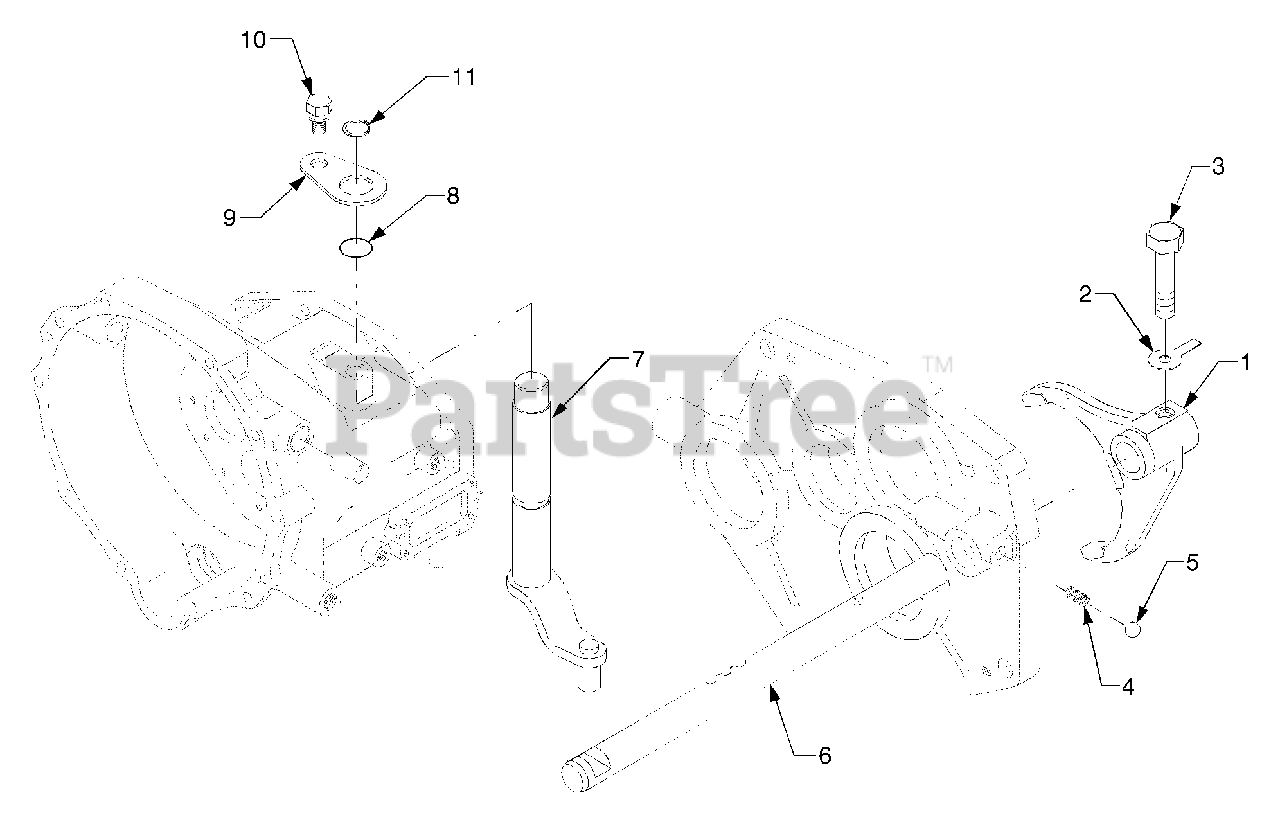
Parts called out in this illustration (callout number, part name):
1	Fork, Shift (Shuttle)
3	Bolt, Stopper
6	Rod, Fork (Shuttle)
7	Arm, Shift (Shuttle)
